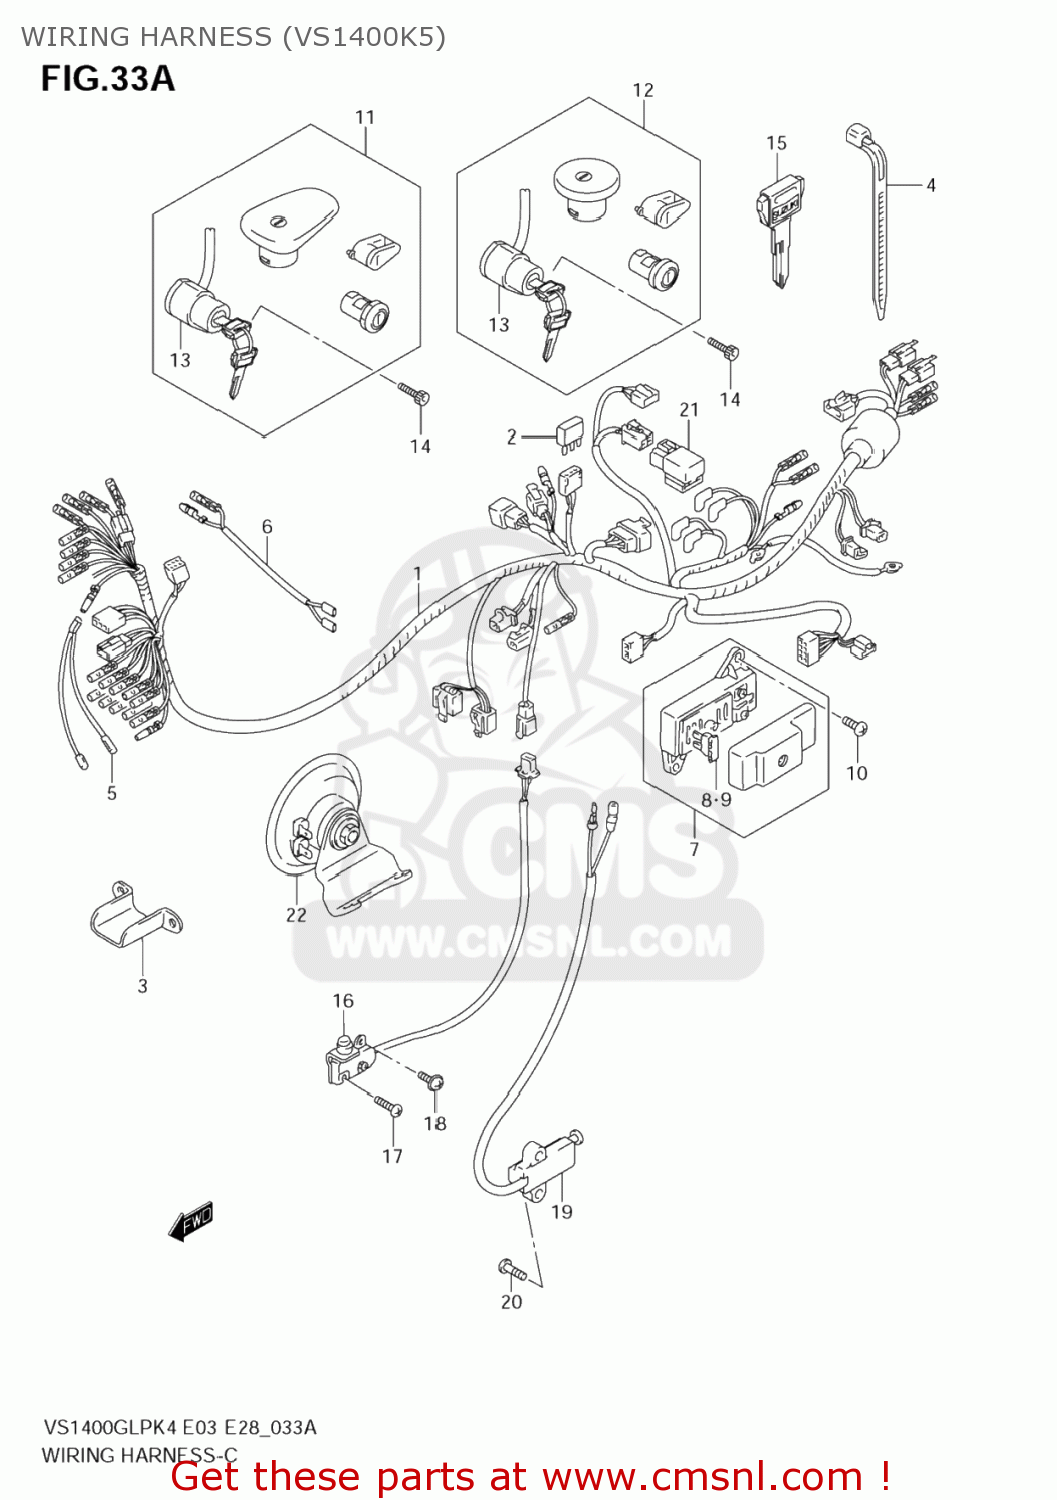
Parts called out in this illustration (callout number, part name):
1	HARNESS,WIRING
2	DIODE(STANLEY DE8804)
3	GUIDE,WIRING HARNESS
4	CLAMP(L:125)
5	WIRE,CLUTCH SW CONNECTOR
6	WIRE,HORN LEAD
7	BOX ASSY,FUSE
8	FUSE (25A)
9	FUSE(10A)
10	SCREW
11	LOCK SET
12	LOCK SET
13	SWITCH ASSY,IGNITION
14	BOLT
15	KEY,BLANK(TYPE:C)
16	SWITCH ASSY,STOP LAMP
17	SCREW 4X16
18	SCREW
19	SWITCH ASSY,SIDE STAND
20	SCREW
21	RELAY ASSY
22	HORN ASSY
